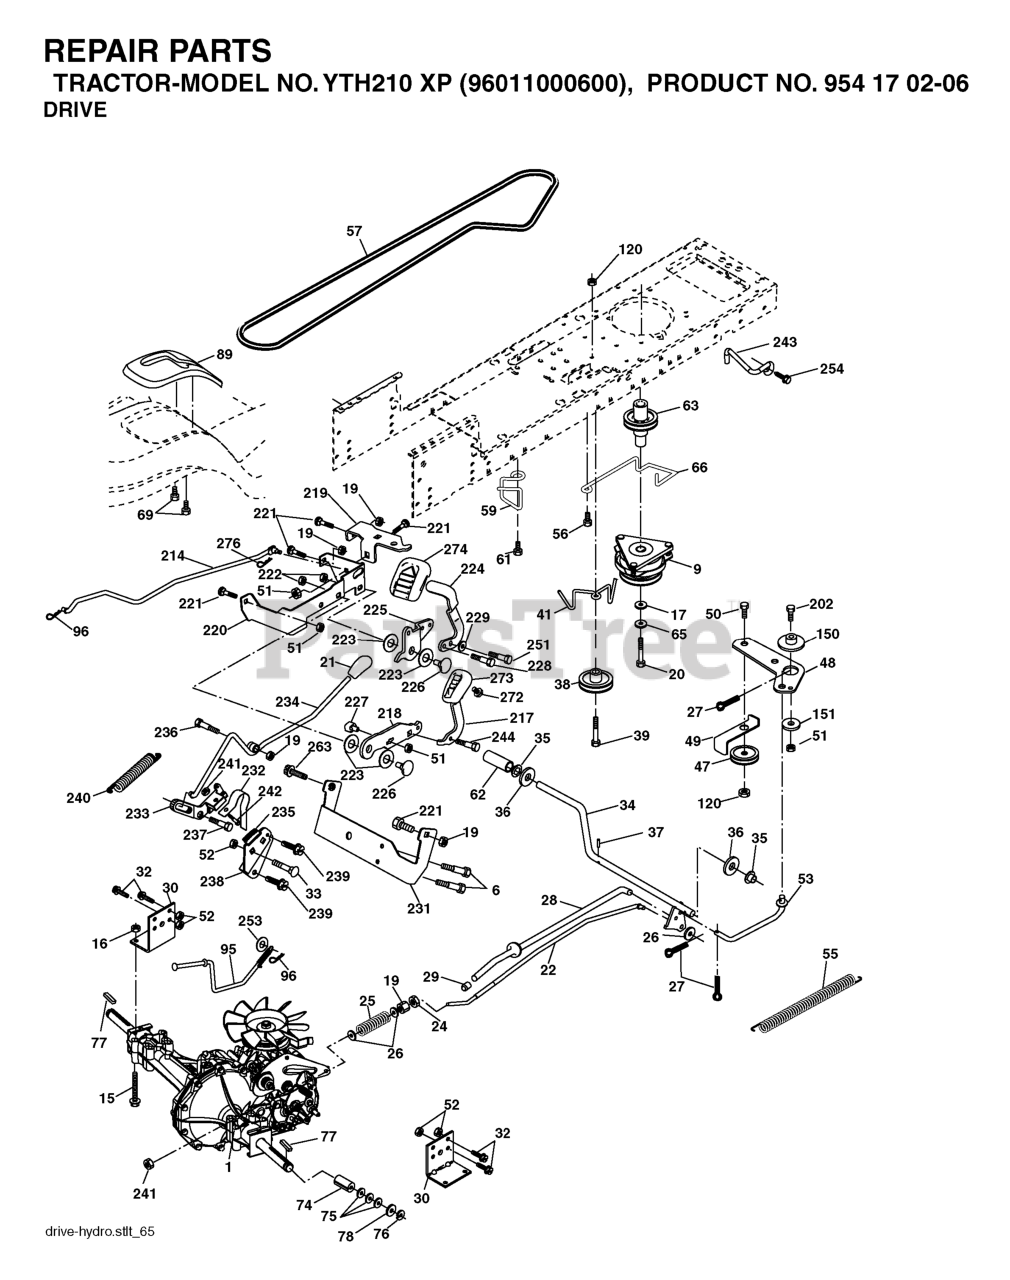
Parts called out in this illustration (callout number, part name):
6	SCREW 5/16"
15	BOLT HEX 5/16-18 GR 5
16	NUT.71038.31-18.HEX.NYLOCK
19	NUT
20	BOLT HEX 7/16-20X4-1/4"
22	ROD.BRAKE.HG-0510.PEDAL.CONTRL
24	NUT
25	SPRING BRAKE ROD
26	WASHER
27	COTTER PIN
28	ROD, PARKING BRAKE
29	PLUNGER CAP
30	BRKT, TRNSXLE MNT 20"
32	BOLT
33	RP BOLT 5/16-18 X3/4 ZN/YEL GR
34	SHAFT, FOOT PEDAL
35	BEARING.NYLON
37	DRIVE PIN
38	PULLEY IDLER COMPOSITE
41	KEEPER, BELT IDLER
47	IDLER PULLEY
48	BELLCRANK, CLUTCH
49	RETAIN BELT
50	BOLT.3/8-16X1.50
52	LOCKNUT
53	LINK, CLUTCH LT
55	SPRING, RETURN LT
56	SCREW.3/8-16
57	DRIVE BELT, LTH & YTH TRACTORS
59	KEEPER, BELT CENTER
61	SCREW 3/8-16X.875
62	COVER, PEDAL (1 2)
63	PULLEY- ENGINE
65	LOCKWASHER
66	KEEPER BELT ENGINE
69	SCREW.HI-LO.CONSOLE
74	SPACER AXLE
77	SQUARE KEY
95	ROD BYPASS
96	RETAINER M
120	NUT LOCK FLG 3/8-16 UNC
150	SPACER, RETAINER
151	WASHER 12/32X2X10GA
214	LINK TRANSAXLE
217	PEDAL REVERSE
218	ARM CONTROL PEDAL REVERSE
219	BRACKET FREST PDL
220	BRACKET MTG.PDL CONTROL
221	Bolt - Rd. Hd. Sq. Neckiage 3/8 16 x 3/4
222	Nut, Crownlock Hex 7/16-14 unc
223	WASHER NYLON
224	PEDAL FORWARD
225	ARM CONTROL PEDAL FORWARD
226	BOLT PIVOT SPACER
227	CAM REVERSE PEDAL LT
228	BOLT SHOULDER
229	WASHER.SERRATED.5/16X.75
231	STRAP TORQUE
232	ACUATOR CRUISE DISENGAGE
233	PAWL CONTROL CRUISE
234	LEVER CONTROL CRUISE
235	SECTOR CONTROL CRUISE
237	SHOULDER BOLT 5/16-18TT
238	ARM MTG.CRUISE SECTOR
239	Screw 5/16-18 x 1/2 Hex, Self Tapping 5/16-18 x 1/2
240	SPRING RETURN CRUISE CONTROL
241	NUT CENTERLOCK
242	BOLT
243	BRACKET, ANTI-ROTATION
244	CAPSCREW.HXHD.FLG.5/16-18X.625
251	SCREW 5/16-18X1
254	SCREW 3/8-16X1
263	SCREW, 3/8-16X3/4
272	SCREW, 5/16-18 X 1/2
274	COVER PEDAL FORWARD
276	CLIP RETAINER
